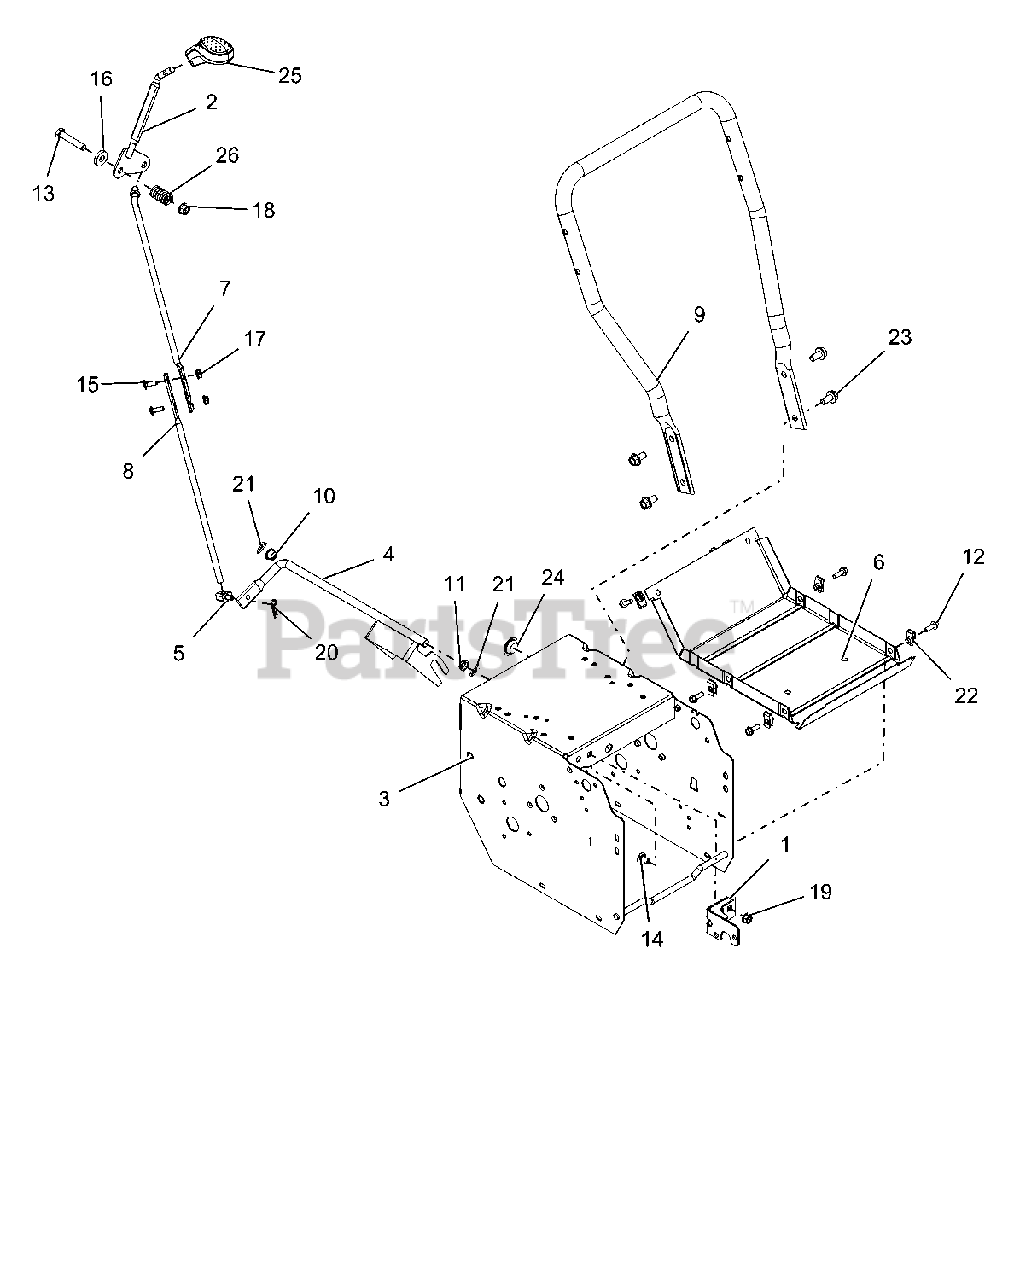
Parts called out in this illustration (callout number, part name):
1	WMT-FRAME BRACKET
2	LEVER, CONTROL-SHIFT(WELDMENT)
3	WELDMNET, FRAME-DELUXE 16"
4	WELDMENT, SHIFT FORK
5	PIVOT,SHIFT ROD .375-16(TRUNN)
6	COVER, BOTTOM
7	ROD, SHIFT - UPPER
8	ROD, SHIFT - LOWER
9	HANDLEBAR, LOWER - SM DELUXE
10	BUSHING, POLYLINER-.50 SPLIT
11	BUSHING, POLYLINER-.50 SNAPIN
12	BLT-HEX .25-20X.75 HWH YZ GR5
13	BLT-HEX .38-16X2.00 GR5 YWZC
14	BLT-RHDSSQNK .31-18X.62 G5YZ
15	BLT-RDHDSQNK .25-20X.75 G5YZ
16	WSHR-FL-STL .406X1.00X.188 YWZ
17	NUT-LK-CTR-FLG .25-20 YWZC
18	NUT-LK-TOP-FLG .38-16 YWZC
19	NUT-LK-TOP-FLG .31-18 YWZC
20	PIN-HAIR INT .08X.18X1.18 YWZC
21	CLIP, SPRING
22	NUT-RTNR .25-20X.56
23	BLT-SERHFWH .38-16X.75 YWZC
24	PLUG, HOLE - .875" NYLON
25	KNOB, CONTROL, DASH
26	SG-COMP .125X.781X1.250
